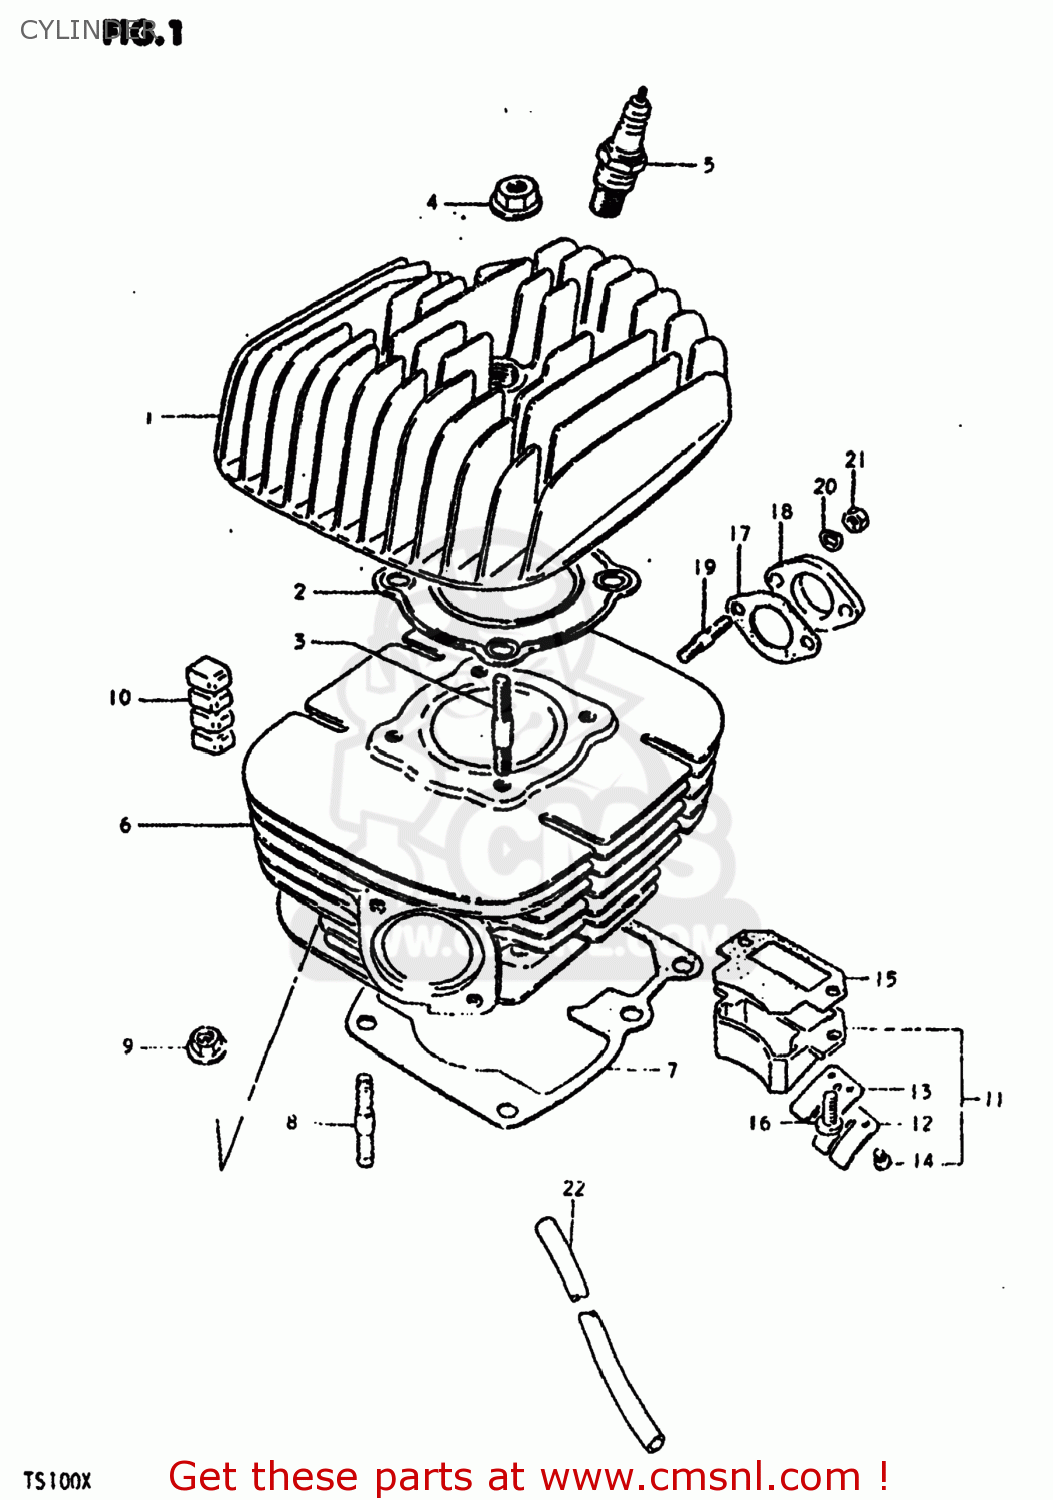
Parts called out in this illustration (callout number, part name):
1	HEAD,CYLINDER
2	GASKET,CYLINDER HEAD (MCA)
3	STUD BOLT
4	NUT
5	SPARK PLUG
6	CYLINDER
7	GASKET,CYLINDER (MCA)
8	STUD 8X25
9	NUT
10	PAD,CYLINDER
11	VALVE ASSEMBLY,REED
12	STOPPER,REED VALVE
13	VALVE,REED
14	SCREW,REED VALVE
15	GASKET,REED VALVE (MCA)
16	SCREW
17	GASKET,CARBURETOR (MCA)
18	INSULATOR,CARBURETOR
19	STUD BOLT
20	LOCK WASHER
21	NUT
22	HOSE
